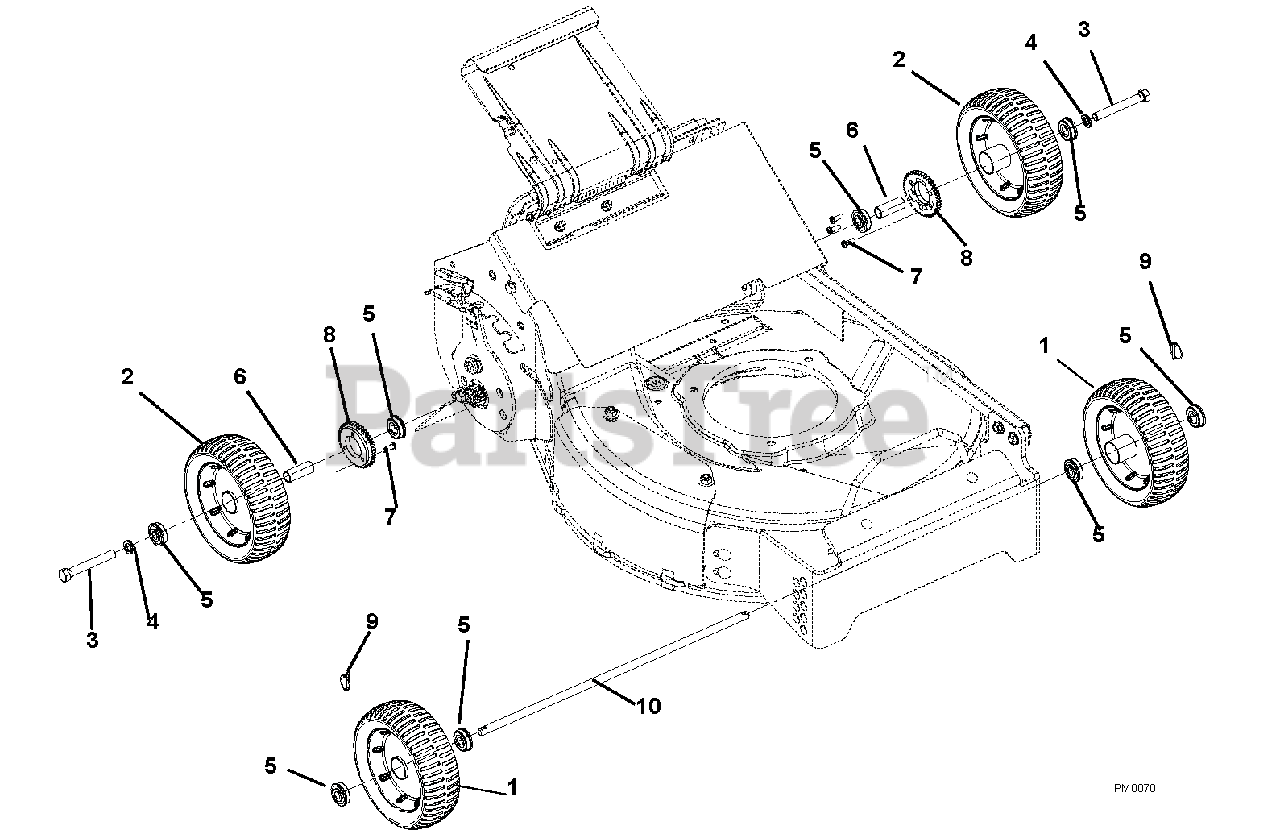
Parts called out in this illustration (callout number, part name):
1	WHEEL ASSY,8.25X2.75 FRONT
2	WHEEL ASSY,8.25X2.75 REAR
3	@BLT-HEX .50-13X3.75 GR5 YWZC
4	@WSHR-LK .50X.125 REG YWZC
5	BRG-BALL .500X1.38X.437
6	SPACER,WHEEL
7	SCR-TAP 1/4-20X3/4 LPAN TL BZ
8	GEAR, WHEEL
9	PIN-KLIK 1.000X.188X1.25 YWZC
10	AXLE SHAFT
